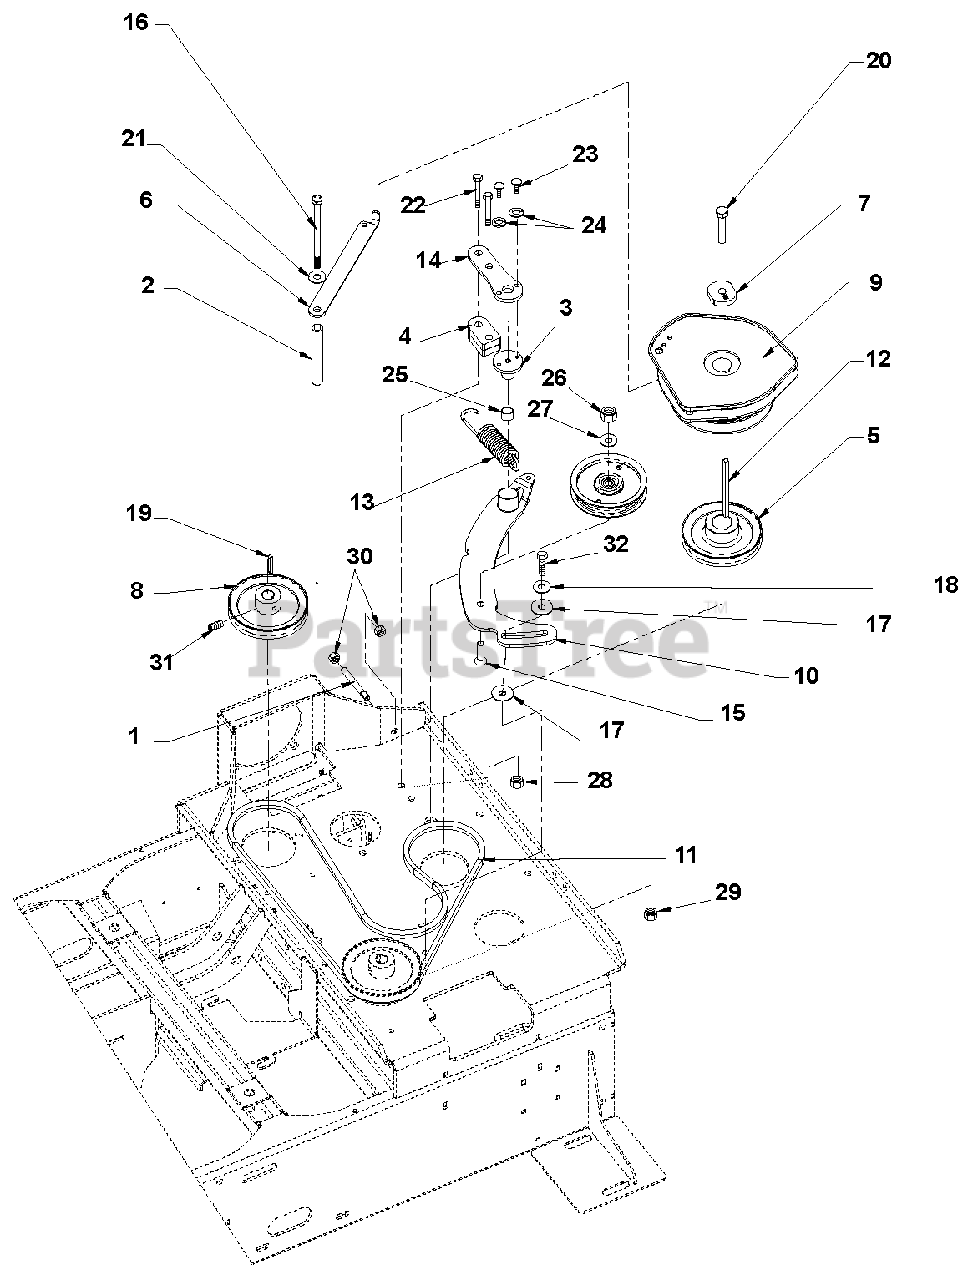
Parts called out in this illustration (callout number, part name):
1	Rod - Threaded Adjustment
2	Tube, RD .625 x .120 x 4.50
3	Pin, Tensioner Pivot
4	Plate, Spacer- Pump TESIONER
5	Pulley, V-Belt 5.00 x 1.13 w/key
6	Plate, Clutch Stop
7	Washer, Clutch Universal
8	Pulley - Pumps 4.78 PD 17MM
9	Clutch, ELECT - OGURA, GT3.5
10	Z Pump Belt Idler Arm Weldment
11	Belt, HA 64.2 EL (Hydraulic Pump)
12	Key, .25 X .25 X 4.62 SQr
13	Spring, EXT 1.188 x .162 x 4.25
14	Plate, Pump Tensioner Top
15	Bolt, .38-16 x 1.50 Flat Socket
16	Bolt, 3/8-16 x 5.50 HEX 5
17	Washer, .400 x 1.27 x .062 Nylon
18	Washer, .406 x 1.00 x .060 Flat
19	Key, M5 x M5 x M36 RE
20	Bolt, 7/16-20 x 2.25 HEX 5
21	Washer, .375 Medium Spring Lock
22	Bolt, .38-16 x 2.00 Hex 5
23	Bolt, 1/4-20X.500 Hex 5
24	Washer, .250 Medium Spring Lock
25	Bearing, Sleeve .753 x .878 x .750
26	Locknut, .38-16 Whiz
27	Washer, .390 x .750 x .080 Flat
28	Locknut, .38-16 Crown
29	Locknut, 5/16-18 Whiz
30	Nut, .38-16 Standard Hex Grade 5
31	Set Screw, 5/16-18 x .625 Square Cup
32	Bolt, .38 x .500 x 5/16-18
